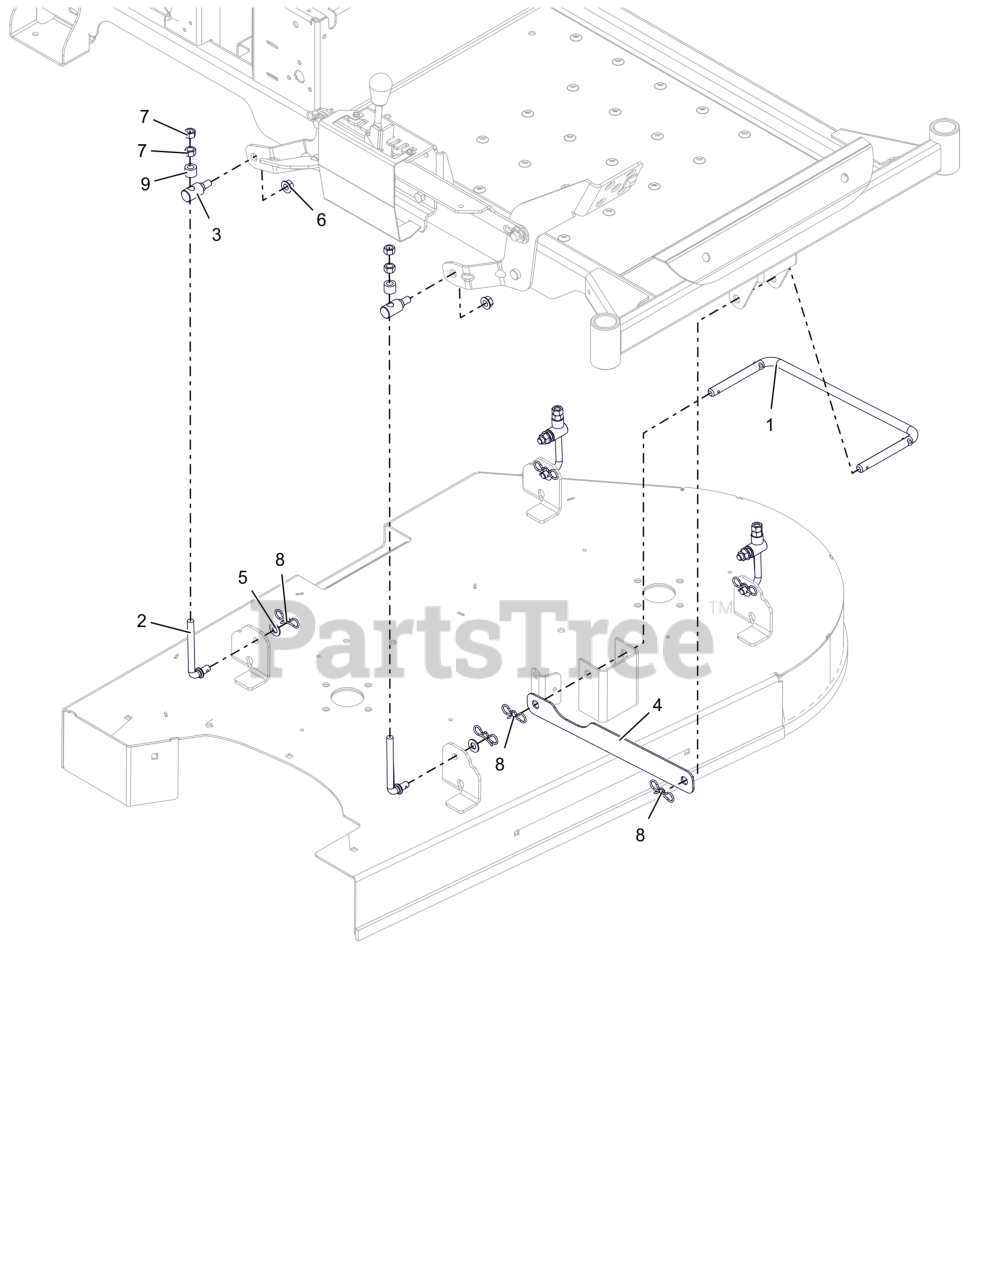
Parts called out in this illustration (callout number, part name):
1	WIREFORM, DRAG LINK
2	WIREFORM, DECK ADJUSTMENT
3	TRUNNION, DECK ADJUSTER
4	STRAP, DRAG LINK
5	WSHR,FLT .406X.812X.065 ZCC
6	NUT-LK-CTR-FLG .375-16 GF ZCC
7	NUT-STD .375-16 G2 ZCC
8	PIN, BOWTIE .091X1.875 ZCC
9	BSHG-SLV .391X.688X.52 PM
